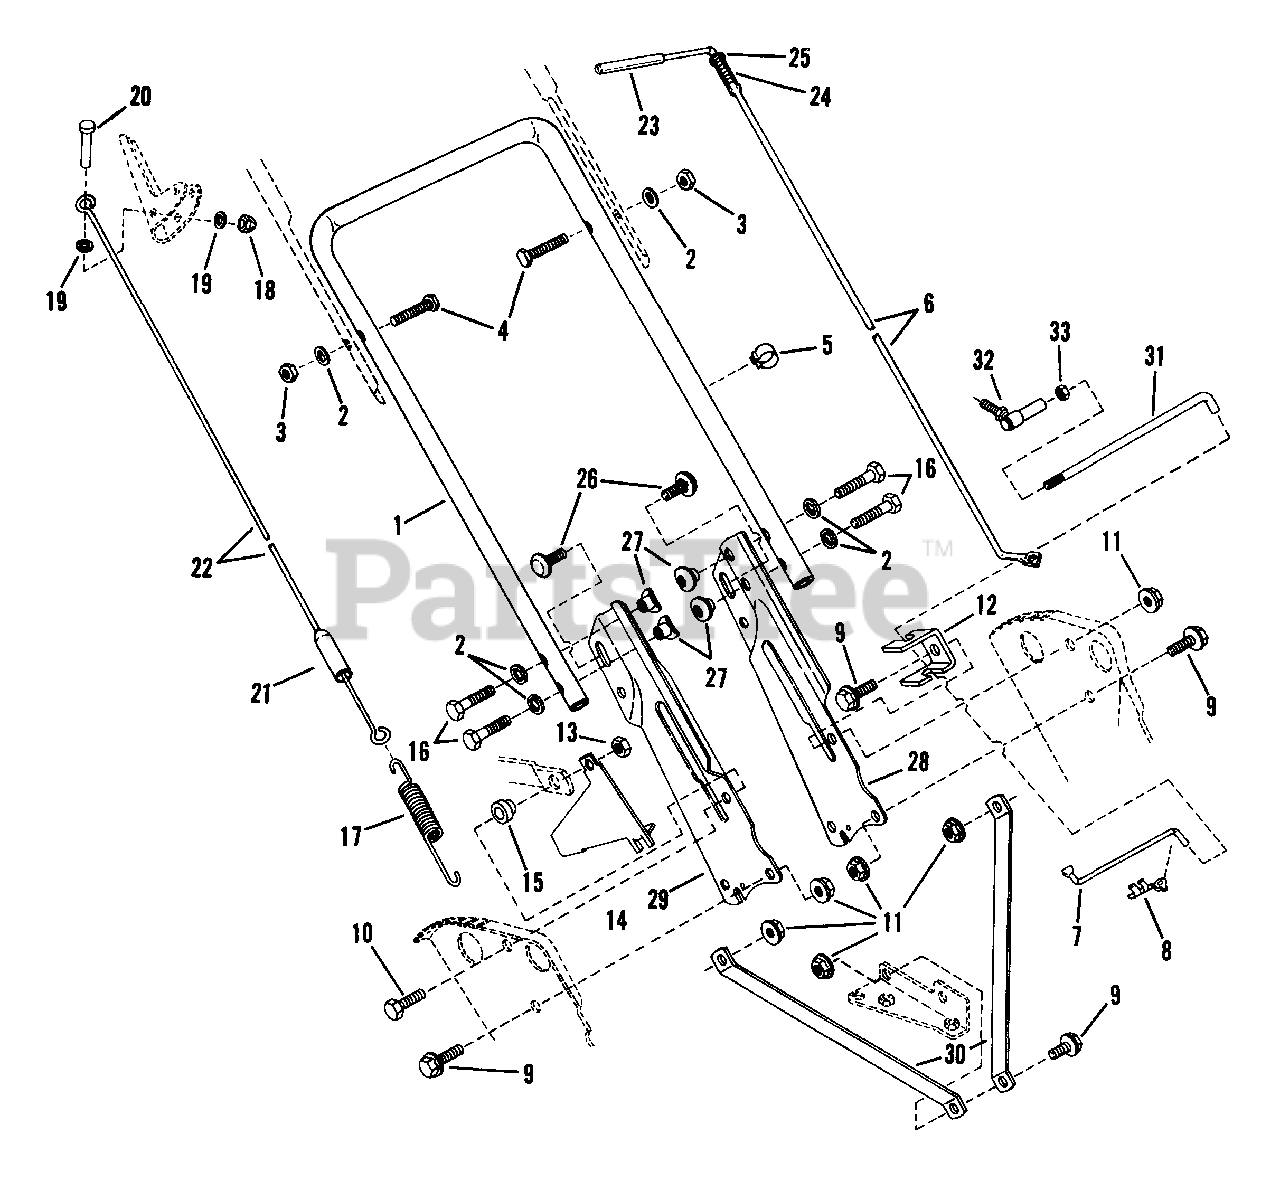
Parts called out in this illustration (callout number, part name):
1	HANDLE, Middle
2	WASHER, 1/4 Int. Tooth Lock
3	NUT, 1/4-28 Hex
4	SCREW, 1/4-28 Hex
5	CLIP, Cable
6	LEVER, Speed Control
7	ROD, Transfer
8	CLIP, Transfer Rod
9	BOLT, 5/16-18 x 3/4" Hex Flange Lock
10	SCREW, 5/16-24 x 1" Hex Head Cap
11	NUT, 5/16-18 Hex Flange Lock
12	ANCHOR, Speed Control
13	NUT, 5/16-24 Hex Centerlock
14	GUIDE, Lower Belt
15	BUSHING, Differential
16	SCREW, 1/4-20 x 1" Hex Head Cap
17	SPRING, Clutch
18	PUSH-NUT
19	WASHER, #10 Flat
20	PIN, 3/16 x 1 3/4" Clevis
21	COVER, Vinyl
22	ROD, Clutch Pull
23	GRIP
24	SPRING
25	WASHER, 3/8" Flat
26	BOLT, 5/16-18 x 5/8 Carriage
27	T-NUT, 1/4-20 Curved Head
28	MOUNT, L.H. Handle
29	MOUNT, R.H. Handle
30	STRAP, Handle
31	LINK, Transfer
32	JOINT, Ball
33	NUT, 1/4-28 Hex
